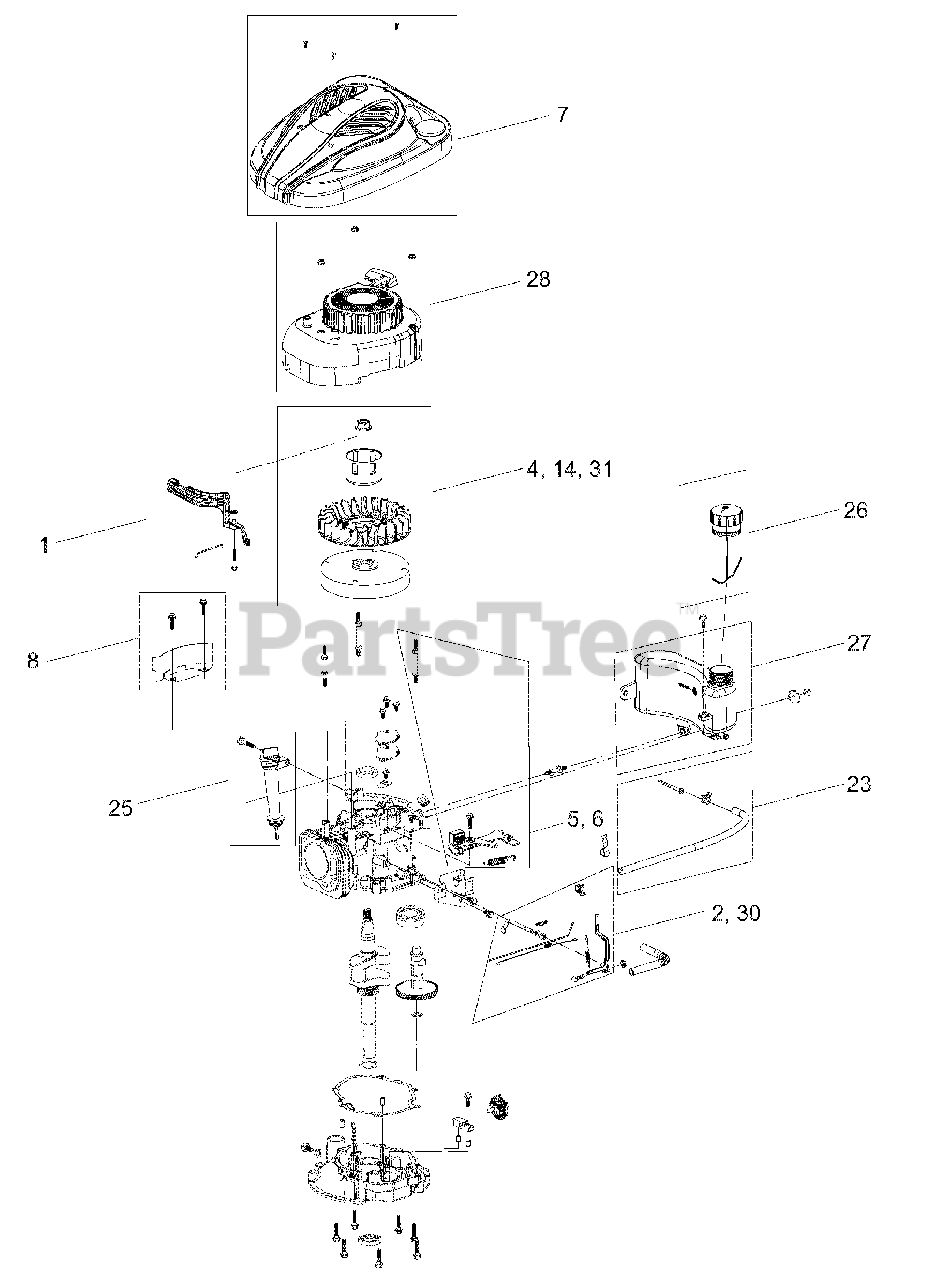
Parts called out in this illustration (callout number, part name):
1	AIR VANE CHOKE KIT
2	GOVERNOR ARM KIT
3	MUFFLER AND SHIELD KIT
4	FLYWHEEL AND FAN KIT – RECOIL START
5	KIT BRAKE ASSEMBLY – RECOIL
6	KIT BRAKE ASSEMBLY – ELECTRIC
7	KIT ARIENS STYLE
8	KIT FLYWHEEL SHIELD
9	THERMAL CHOKE CONTROL KIT
10	KIT-AIR CLEANER ASM, 2 HINGE
11	CARBURETOR COMPLETE KIT
12	IGNITION COIL KIT
13	SEAL AND GASKET KIT
14	FLYWHEEL AND FAN KIT – ELECTRIC START
16	STARTER KIT – ELECTRIC START
17	WIRE HARNESS KIT
18	KIT-VALVE COVER (1P65FA)
19	LOCK-THROTTLE
20	STUD-INTAKE
21	AIR FILTER, FOAM PRE-FILTER
22	AIR FILTER ELEMENT
23	FUEL LINE WITH STRAINER
24	SPARK PLUG
25	OIL FILTER TUBE/CAP
26	GAS CAP WITH CANISTER
27	FUEL TANK
28	RECOIL ASSEMBLY
29	ENGINE, SERVICE, AC SERIES
29	ENGINE, SERVICE, AC SERIES, ELEC
30	GOVERNOR ARM KIT – BBC
30	KILL SWITCH, ENGINE – BBC
31	FLYWHEEL AND FAN KIT – BBC
